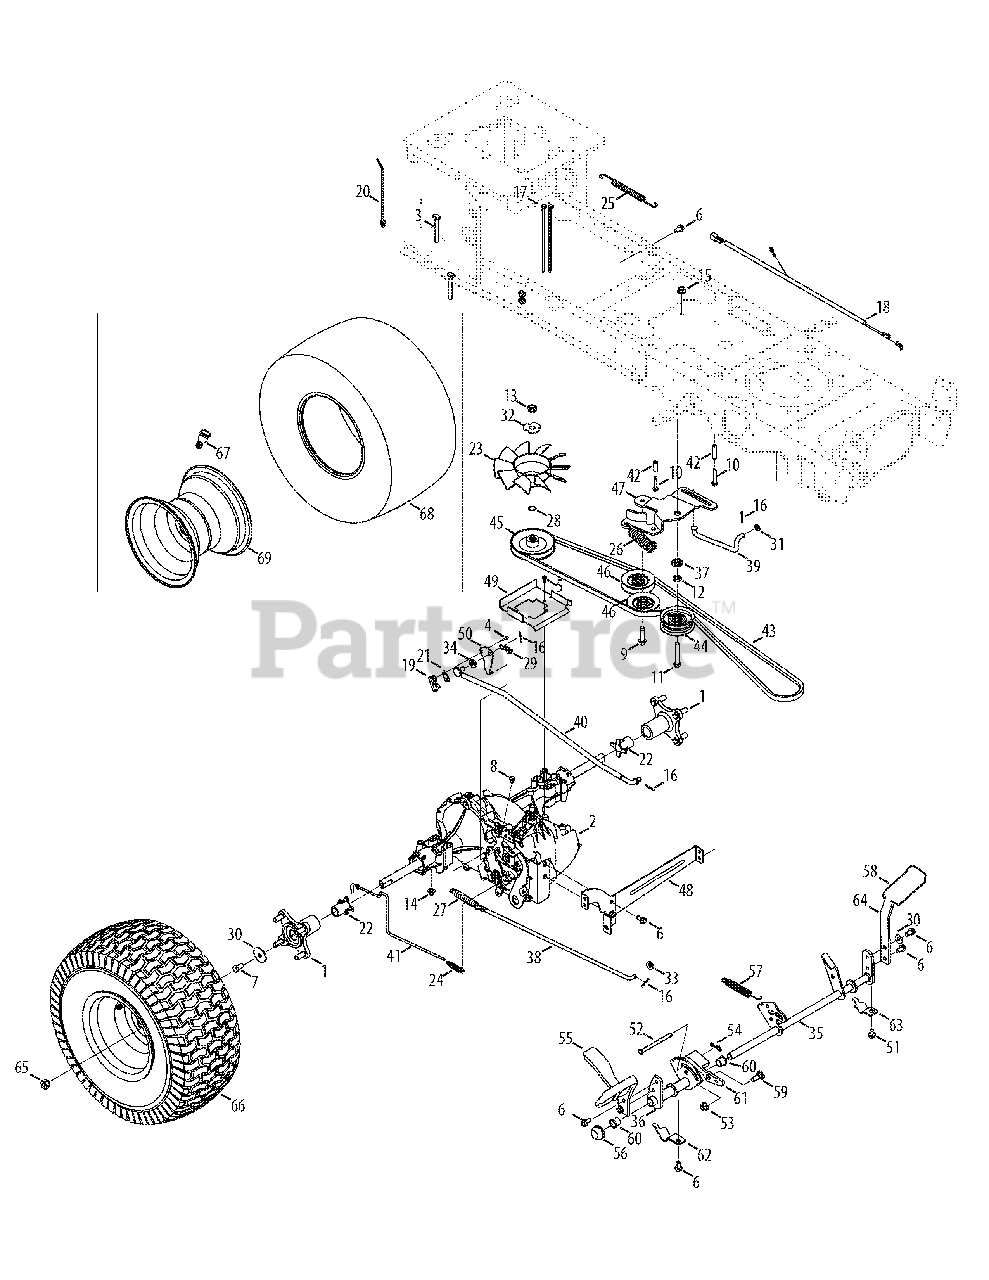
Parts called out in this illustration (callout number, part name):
1	Wheel Hub Assembly
2	Hydro Transmission
3	Hex Head Screw, 5/16-18:2.75
4	Screw, Indented Washer, #8-18:0.500
5	Screw, #10-16:0.500
6	Taptite Screw, 5/16-18:.750
7	Hex Head Screw, 5/16-24:.750
8	Taptite Screw, 1/4-20:0.375
9	Taptite Sems Screw, :3/8-16:1.500
10	Taptite Screw, 1/4-20:1.625
11	Hex Head Screw, 3/8-16:2.25
12	Jam Nut, 7/16-20
13	Jamlock Nut, 1/2-20
14	Flangelock Nut, 5/16-18
15	Flangelock Nut, 3/8-16
16	Cotter Pin, 3/32:1.0
17	Cable Tie. 3/16 x .05 x 7.4
18	Jumper Harness
19	Short Spring Switch
20	Push Mount Cable Tie 7.5 LG
21	Insulator Nut Plate
22	Sleeve, .765 ID x 1.500 LG
23	Hydro Fan
24	Extension Spring, .48 OD x 2.03
25	Extension Spring, .500 DIA x 12.6 LG
26	Extension Spring, 1.00 DIA x 4.75
27	Extension Spring, .59 OD x 4.00 LG
28	Wire Ring
29	Extension Spring, .375 OD x 1.44 LG
30	Bell Washer, .340 x .872 x .060
31	Flat Washer, .330 x .630 x .0635
32	Lock Washer
33	Flat Washer, .344 x .750 x .120
34	Flat Washer, .407 x .812 x .135
35	Brake Control Assembly
36	Hydro Pedal Bracket Assembly
37	Shoulder Spacer, 1.375 x .380 x .183
38	Brake Rod
39	Footpedal Bypass Transmission Rod
40	Hydro Control Rod
41	Hydro Bypass Rod
42	Spacer, 260 x .372 x 1.420 LG
43	V-Belt, 4L x 78.9 POLY
44	Flat Idler Pulley, 2.75 OD
45	Input Pulley, 4.13 DIA
46	V Idler Pulley, x 3.06
47	Center Idler Bracket
48	Hydro Mounting Bracket
49	Belt Disengage Support Bracket
50	Switch Actuator Bracket
51	Taptite Screw, 5/16-18:0.625
52	Clevis Pin, 5/16 x 3.985
53	Flangelock Nut, 3/8-16
54	Bow-Tie Cotter Pin
55	Control Pedal
56	Push Cap
57	Extension Spring, .63 DIA x 4.95 LG
58	Brake Pedal Pad
59	Shoulder Bolt, .500 x .270:3/8-16
60	Flange Bearing, .630 ID x .695 OD x .60
61	Cruise Latch
62	Pedal Support Bracket
63	Pedal Support Bracket, 5/8
64	Brake Pedal Bracket
65	Lug Nut
66	Wheel Assembly
67	Tubeless Air Valve
69	Rim Assembly
